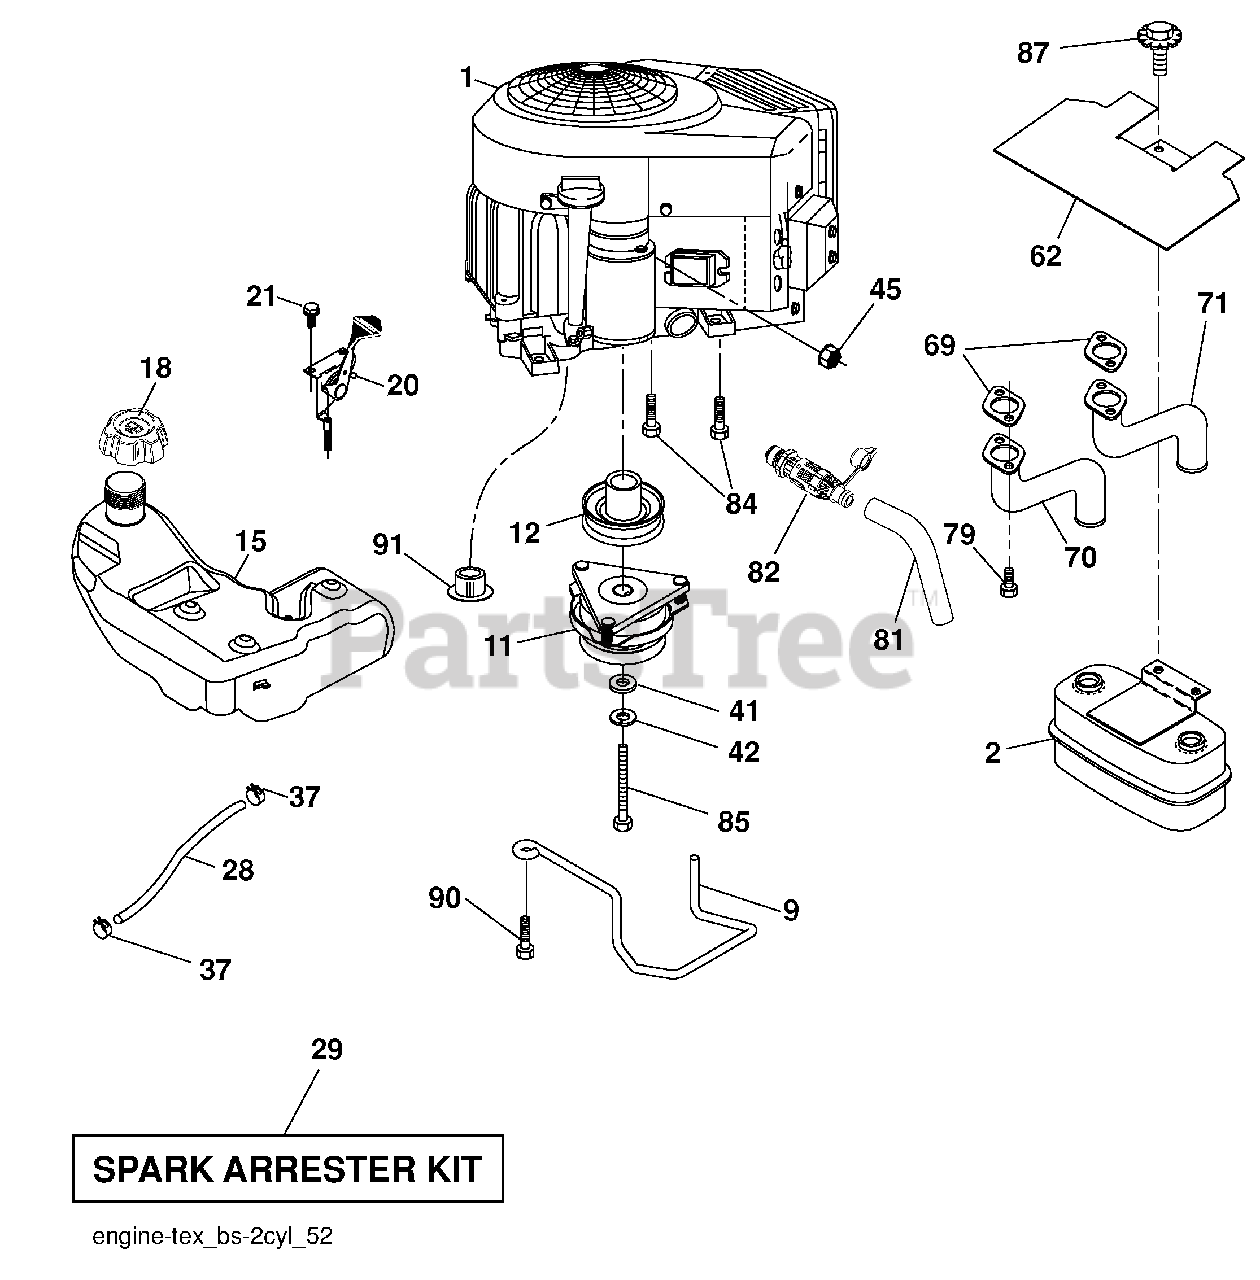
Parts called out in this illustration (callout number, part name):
9	Keeper Belt Engine
11	Clutch Electric
12	Pulley Engine
15	Tank Fuel
18	Cap Asm
20	Control Throttle
21	Screw #10 x 0.750 BOS Thread
28	Fuel Line
29	Spark Arrester Kit
37	Clamp Hose
41	Washer 1-1/2 OD x 15/32 ID x .250
42	Washer Lock 7/16
45	Nut Keps Hex 1/4-20 unc
62	Shield Heat Muffler
70	Tube Exhaust LH
71	Tube Exhaust RH
79	Screw Socket Head 5/16-18 x 1
81	Tube Drain Oil Easy
82	Drain Oil Valve
84	Screw 3/8-16 x 1-1/4
85	Bolt Hex 7/16-20 x 4 Cat. 5-1 THR.
87	Bolt 5/16-18 x 3/4
90	Screw 3/8-16 x 1
